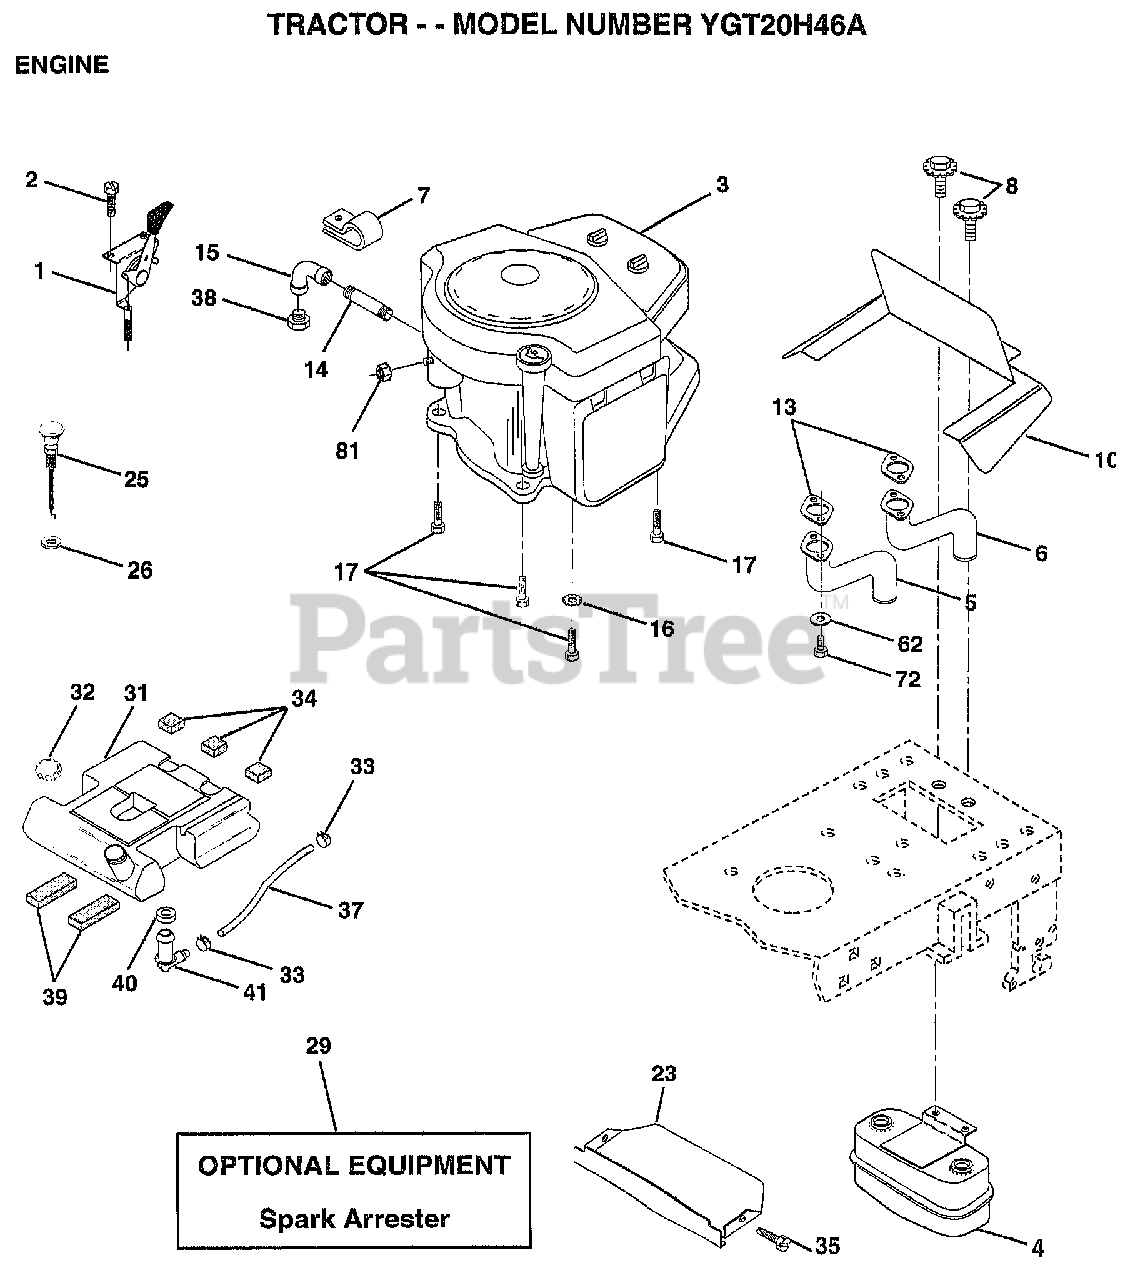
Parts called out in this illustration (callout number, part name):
2	SCREW LT
4	MUFFLER.TW.LOTONE
5	TUBE MANIFOLD LH
6	TUBE MANIFOLD RH
7	"CLIP,INSULATOR"
8	BOLT.5/16-18.UNC
10	SHIELD.BROWNING
14	PIPE NIPPLE LT
15	ELBOW
16	LOCKWASHER
17	SCREW LT
23	SHIELD.BRN/DBR.GD
25	"CONTROL.CHOKE.51"""
26	"NUT,KEPS 3/8-24IM"
31	TANK FUEL REAR
32	CAP ASM FUEL
33	HOSE CLAMP
34	PAD-SPACER LT
35	BOLT.5/16-18.UNC
37	FUEL LINE T
39	PAD IDLER TI
40	BUSHING OUTLET T
41	STEM.TANK.FUEL
62	LOCKWASHER
72	SCREW
81	NUT
